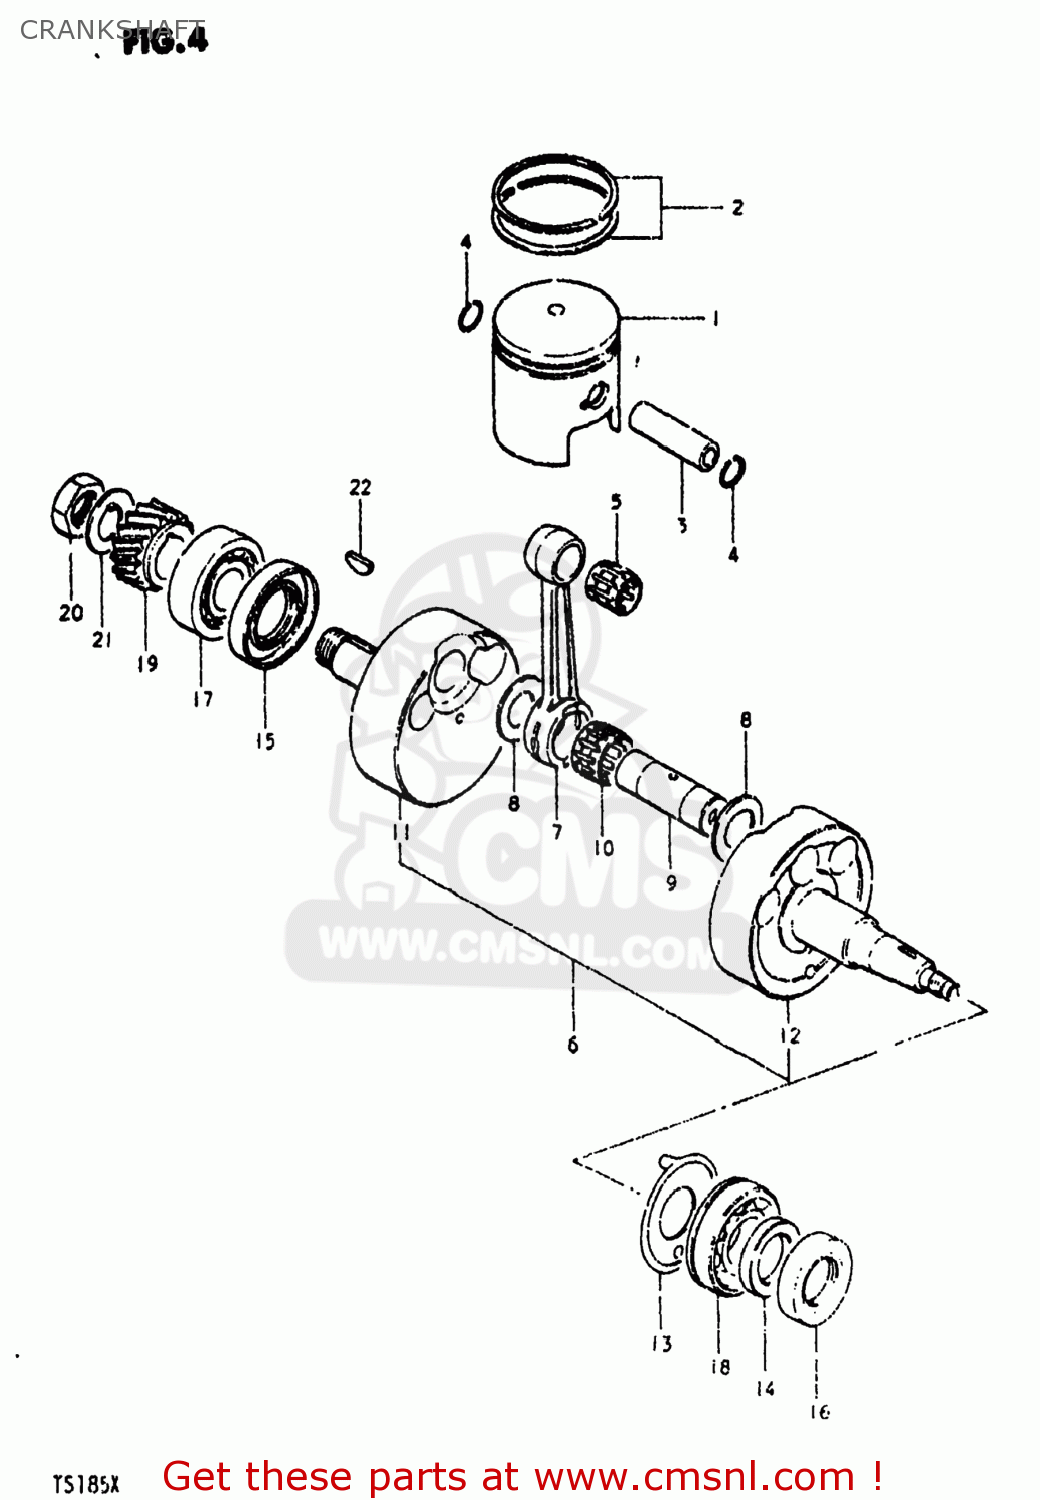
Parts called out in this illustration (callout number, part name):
1	PISTON
2	RING SET,PISTON
3	PIN,PISTON
4	RING,SNAP 16MM
5	BEARING
6	CRANKSHAFT ASSEMBLY
7	ROD, CONNECTING
8	WASHER(22X35X1)
9	PIN,CRANK
10	BEARING 22X28X16
11	CRANKSHAFT,R
12	CRANKSHAFT,LEFT
13	PLATE,CSHAFT OIL GUIDE
14	SPACER(25X34X4.5)
15	SEAL,OIL(26X52X8)
16	SEAL,OIL(25X44X7)
17	BEARING
18	BEARING(25X62X17)
19	GEAR,PRIMARY DRIVE
20	NUT
21	WASHER
22	KEY
